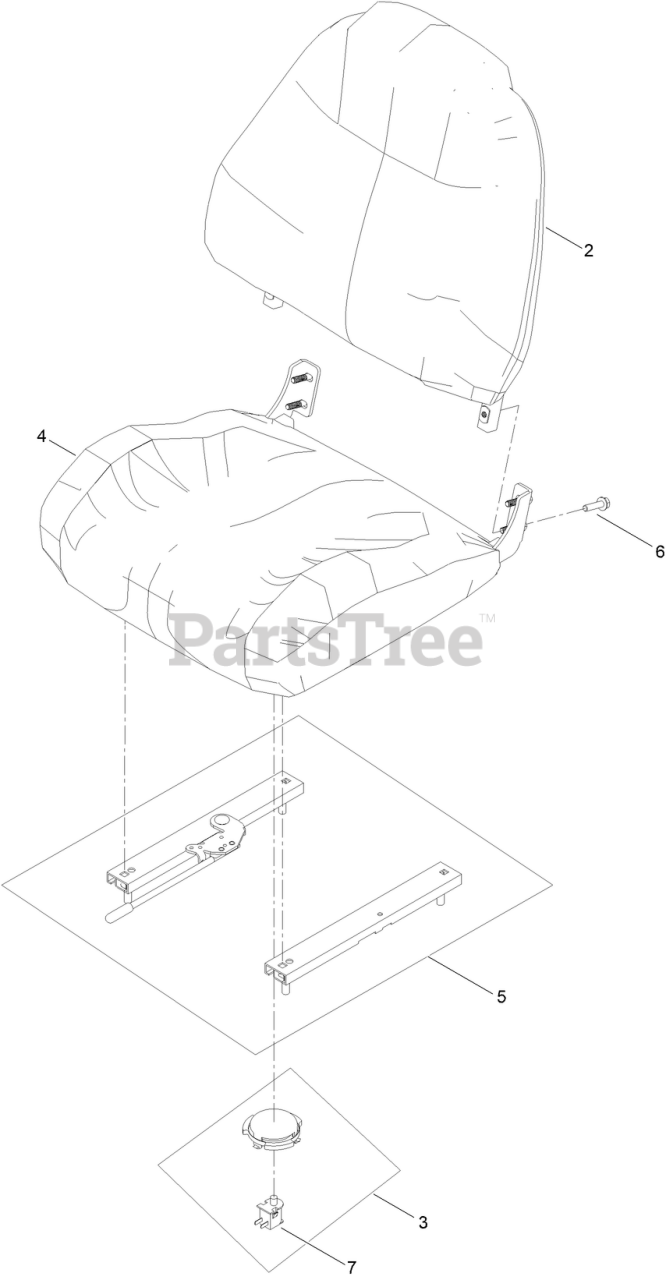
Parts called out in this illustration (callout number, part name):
2	TORO BACK COVER
3	SEAT SWITCH DELTA 6500-02 OPEN
4	TORO SEAT COVER
5	SLIDE ASM-SEAT
6	SCREW-HHF
7	SWITCH-BAIL
